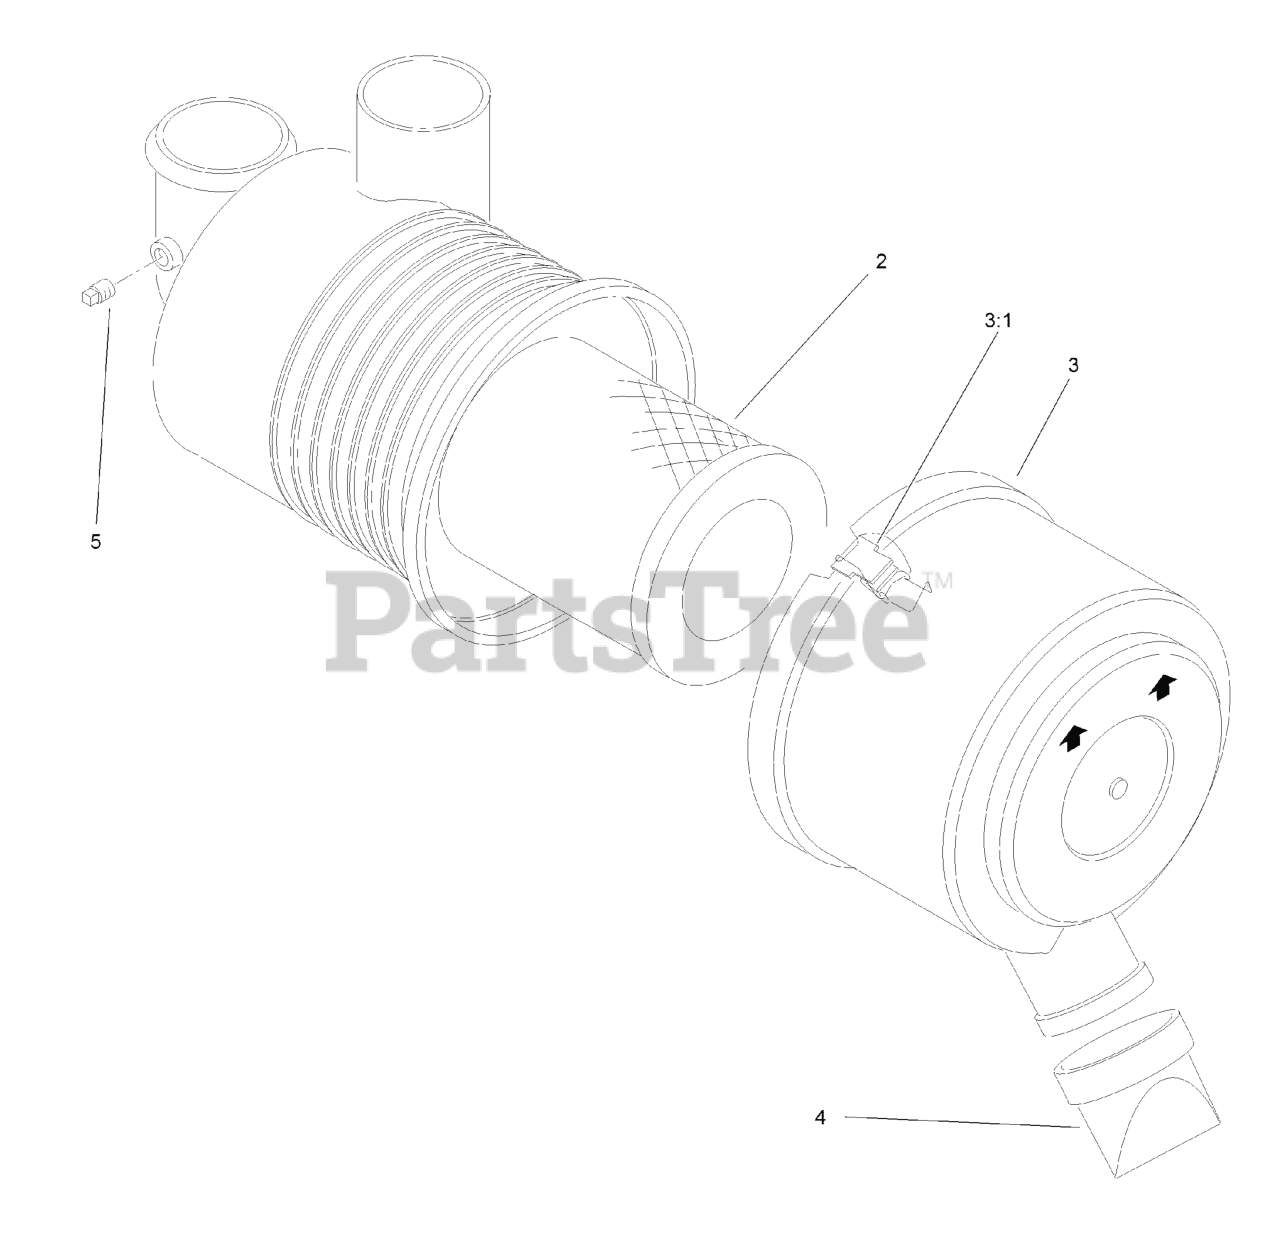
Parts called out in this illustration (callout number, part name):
2	FILTER-AIR
3	COVER ASM
3:1	LATCH-CLEANER, AIR
4	VALVE-VACUATOR
5	PLUG-PIPE
